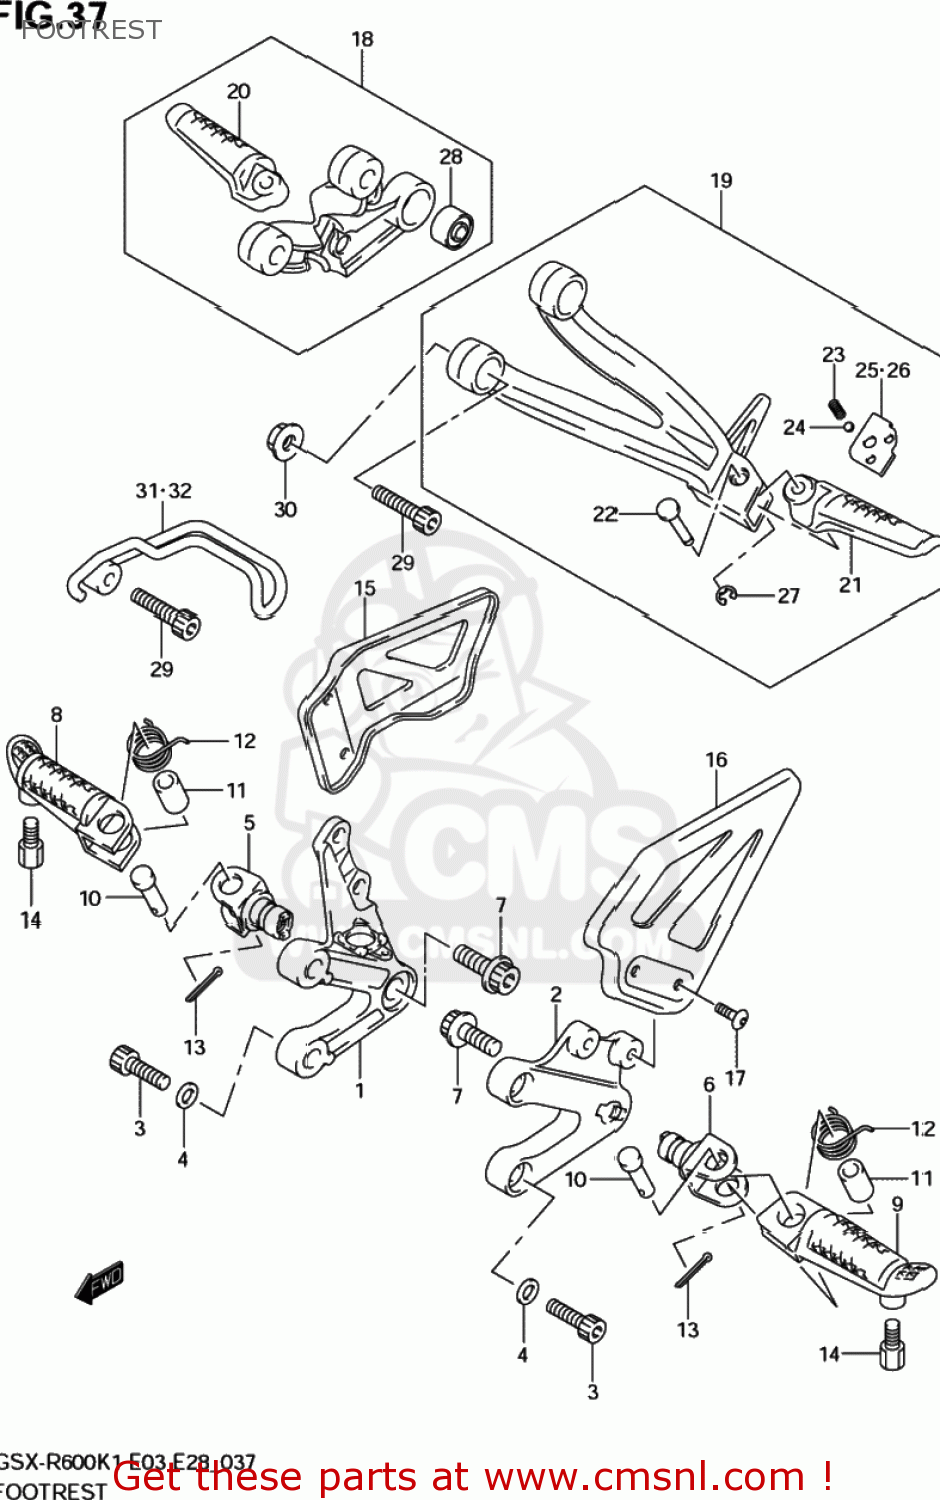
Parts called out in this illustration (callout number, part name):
1	BRACKET,FR FOOTREST,R
2	BRACKET,FR FOOTREST,L
3	BOLT,FOOTREST BRACKET
4	WASHER
5	HOLDER,FOOTRES
6	HOLDER,FOOTRES
7	BOLT(10X28)
8	BAR,FR FOOTREST,R
9	BAR,FR FOOTREST,L
10	PIN
11	SPACER(8.1X12X22)
12	SPRING
13	PIN 20X15
14	BOLT,BANK SENSOR
15	GUARD,FR FOOTREST,R
16	GUARD,FRONT FOOTREST,LEFT
17	SCREW(5X10)
18	FOOTREST ASSY,PILLION,R
19	FOOTREST ASSY,PILLION,L
20	BAR,PILLION FOOTREST,RIGHT
21	BAR,PILLION FOOTREST,LEFT
22	PIN
23	SPRING
24	BALL
25	PLATE,PILLION FOOT,R
26	PLATE,PILLION FOOT,L
27	E-RING
28	BUSH
29	BOLT
30	NUT
31	BRACKET,LUGGAGE HOOK,R
32	BRACKET,LUGGAGE HOOK,L
